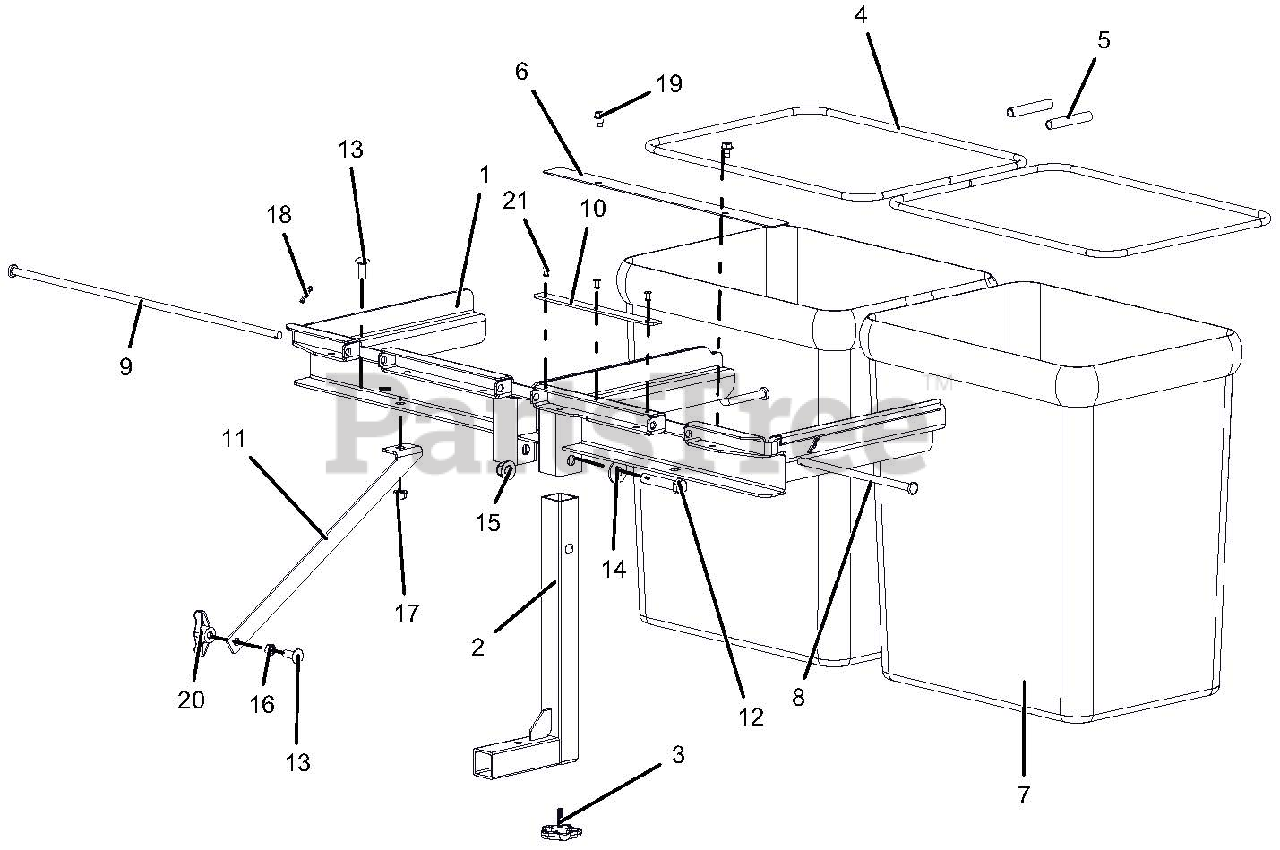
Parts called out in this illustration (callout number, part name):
1	ASM, BAGGER FRAME UPPER
2	WLDMT, BAGGER MOUNT POST
3	KNOB, WING STUDDED
4	FRAME, BAG
5	HOSE, .38 X .50 X 3.00 VINYL
6	BRKT, BAG OVERLAP
7	BAG, MESH /ZOOM
8	PIN, BAGGER HINGE (L)
9	PIN, BAGGER HINGE (R)
10	SEAL, HINGE
11	STRAP, BAGGER SUPPORT
12	BLT-HEX .50-13X2.75 GR8 YWZC
13	BLT-RDHDSHSQNK.38-16X1.0 G5YZ
14	WSHR-FL-STL .531X1.250X.100 YWZC
15	NUT-LK-NYL-FLG .50-13 YWZC
16	NUT, JAM .375-16 YWZC
17	NUT, LK-TOP-FLG .38-16 YWZC
18	PIN-HAIR, ENDRIES #25 YWZC
19	SCR-TAP .31-18X.50 HWH TR YWZ
20	KNOB, WING .38-16 UNC NYL/TALC
21	RVT-POP .187x.527 DOME
